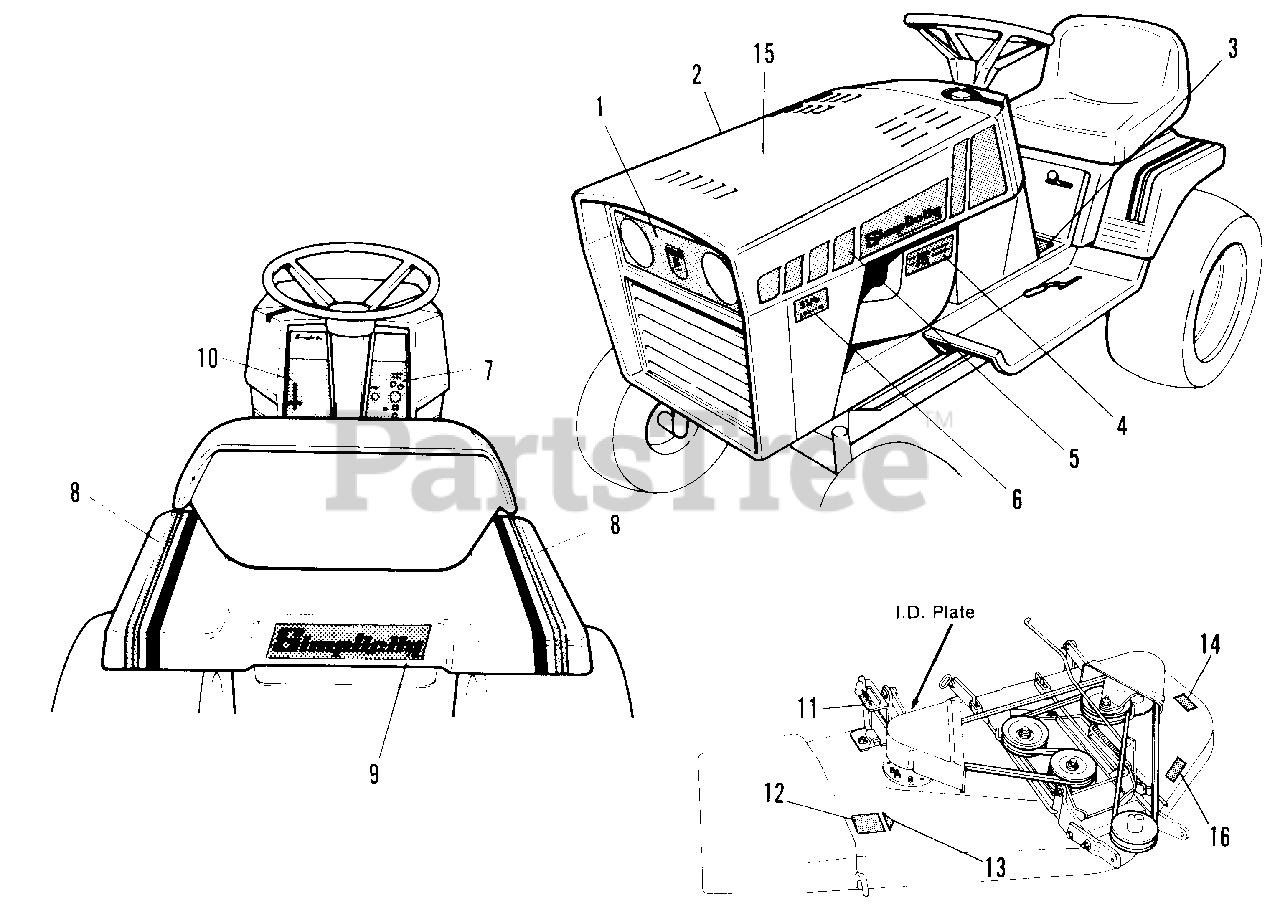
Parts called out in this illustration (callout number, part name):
1	DECAL, Grille
2	DECAL, Hood, R.H.
3	DECAL, Shift
4	DECAL, Engine (1691558)
4	DECAL, Engine (1691431)
5	DECAL, Hood, L H.
6	DECAL, 5216 Special (1691558)
6	DECAL, 5212.5 Special (1691431)
6	DECAL, 5212 Special (1691554)
7	DECAL, Dash, R H. (1691431, 1691558)
7	DECAL, Dash, R.H. (1691554)
8	DECAL, Seat Deck
9	DECAL, Simplicity
10	DECAL, Dash, L.H. (1691431, 1691558)
10	DECAL, Dash, L.H. (1691554)
11	DECAL, Mower Height
12	DECAL, Danger
13	DECAL, OPEI
14	DECAL, Danger
15	DECAL, Drive Belts (Inside Hood)
16	DECAL, Caution
